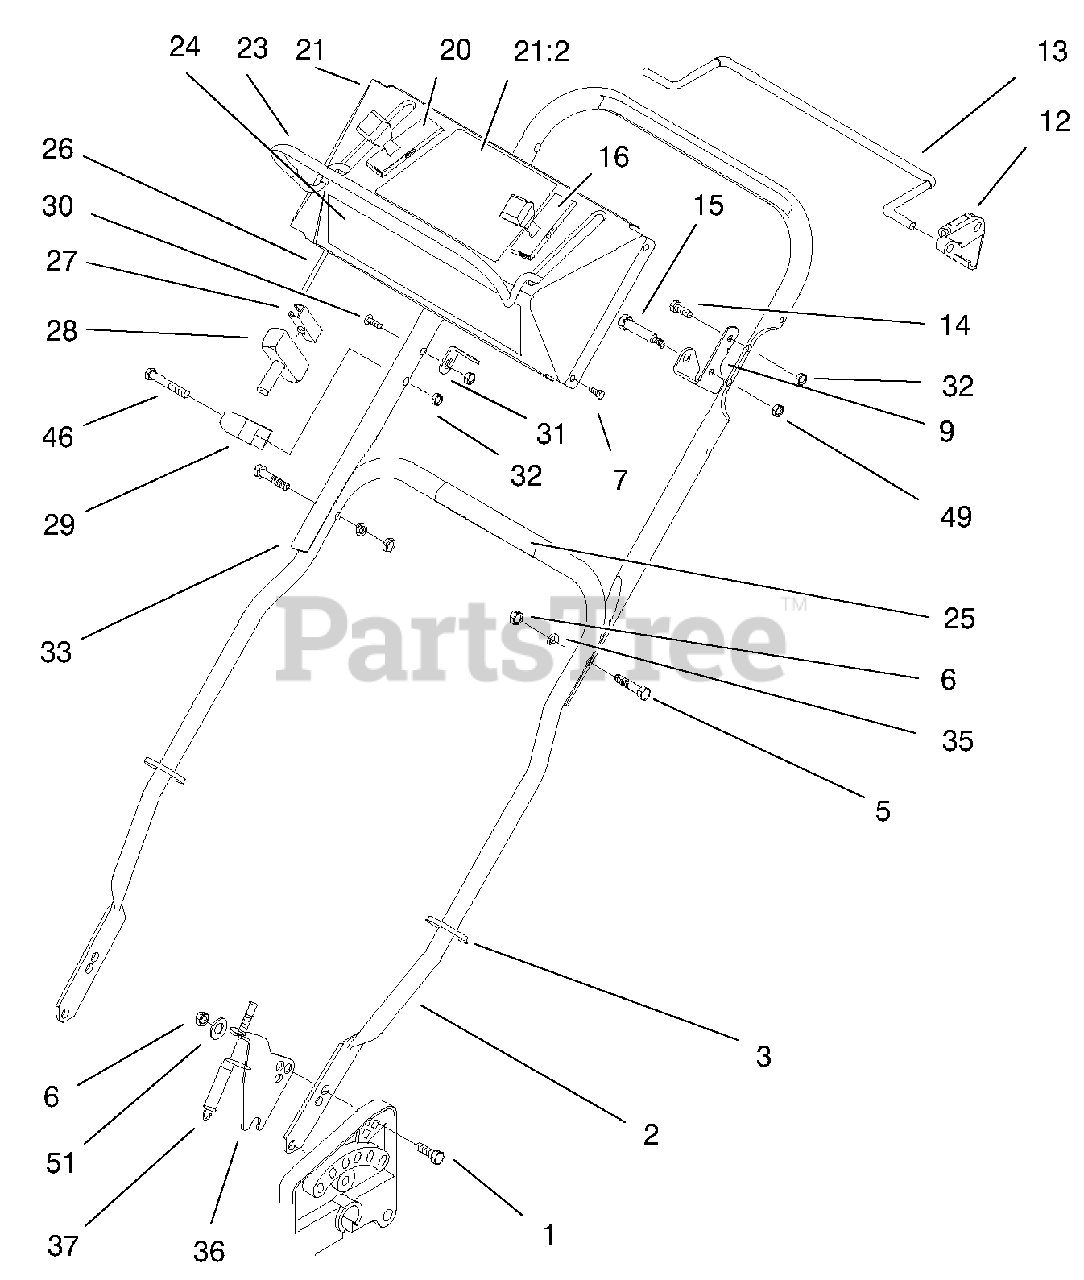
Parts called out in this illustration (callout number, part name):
1	Screw-CARR
2	Handle-Lower
3	Tie Strap
5	Screw-HH
6	Nut-Lock,NI
9	Bracket-Stop, Bail
12	Stop-Pivot
13	Bail-Control
14	Screw-HH
16	Control ASM.-Throttle
20	Cable-Ground Speed
21	Control Panel ASM
21:2	Decal-Control Panel
23	Bail-Engine Control
24	Decal-Console
25	Decal-Operation
26	Brake Cable ASM
27	Starter-Clip
28	Handle-Start
29	Rope-Guide
30	Screw-Handle
31	Bracket-Cable Anchor
32	Nut-Lock NI
33	Handle-Upper
35	Washer-Curved
36	Bracket-Traction Cable
37	Cable-Traction
46	Screw-HH
49	Nut-Lock, NI
51	Washer-flat
